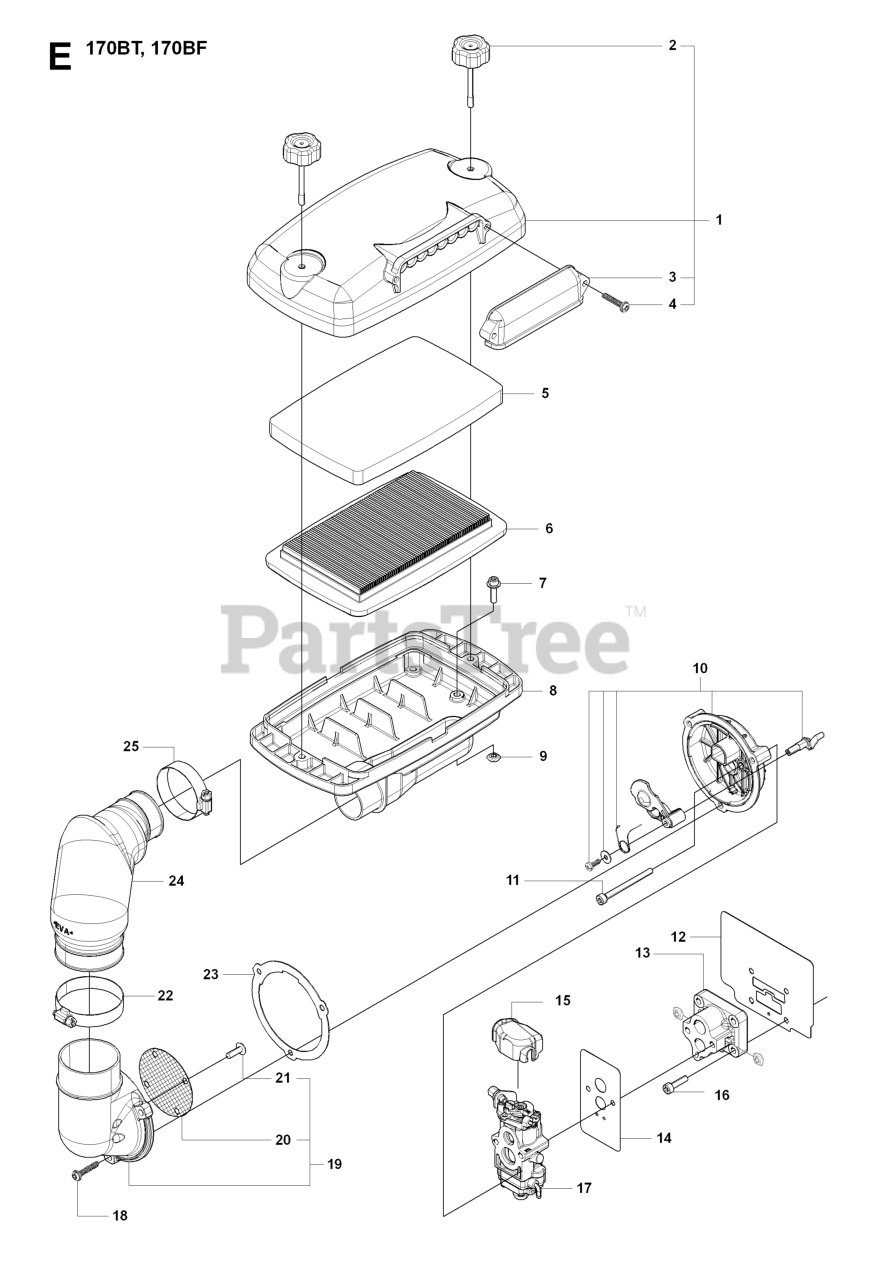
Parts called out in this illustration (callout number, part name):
1	COVER ASSY
5	ELEMENT
6	ELEMENT
17	CARB
19	CUP COVER ASSY
20	SCREEN
22	CLAMP(F64)
25	CLAMP(F51)
